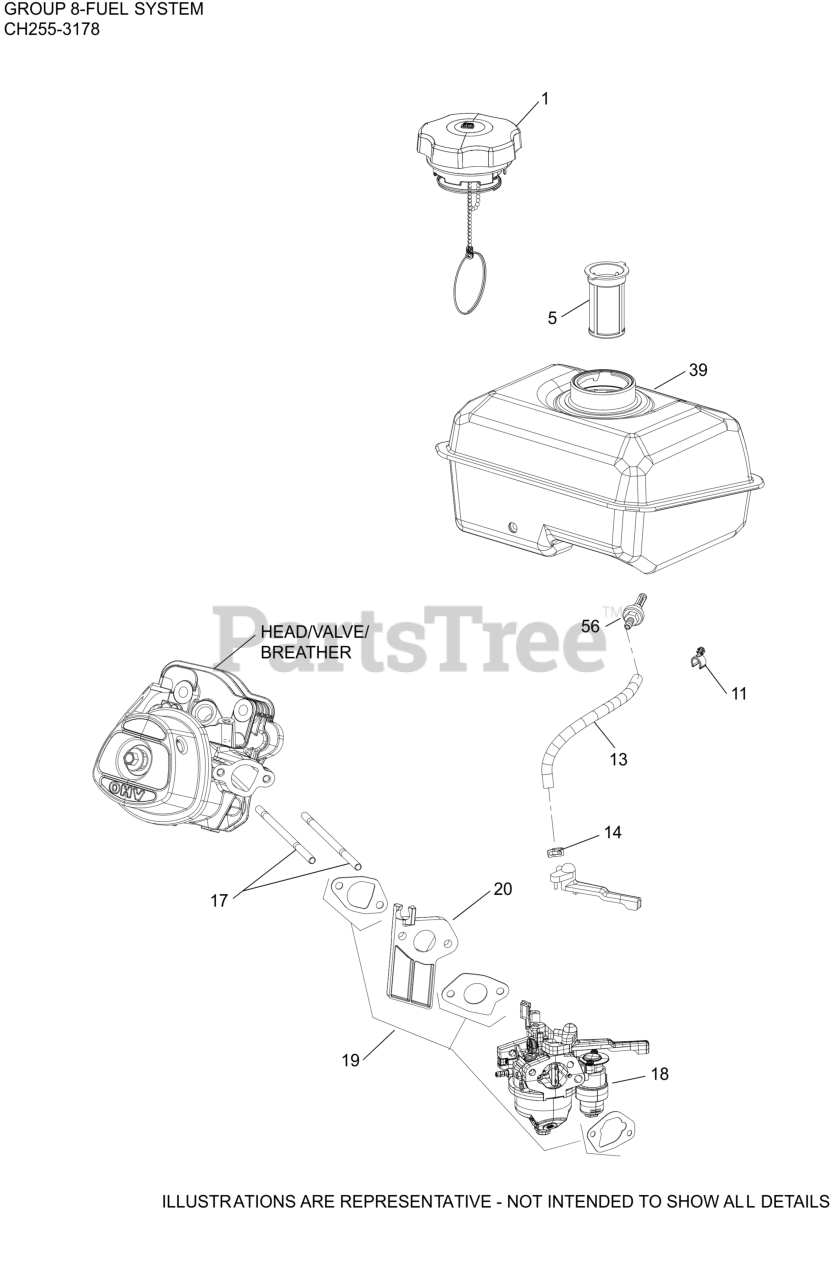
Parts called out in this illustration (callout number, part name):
1	CAP, FUEL ASSEMBLY
5	FILTER, FUEL TANK
11	CLIP, FUEL HOSE
13	LINE, FUEL (10"-CUT TO LENGTH)
14	CLAMP, FUEL LINE
17	STUD, CARBURETOR
18	KIT, CARBURETOR
19	KIT, INTAKE GASKET
20	INSULATOR, CARBURETOR
39	TANK, FUEL ASSEMBLY
56	FITTING, FUEL ASSY
NI	KIT, HIGH ALT (4000-8000 FT)
NI	KIT, HIGH ALT (8,000+ FT)
NI	KIT, CARBURETOR REPAIR (RUIXING)
